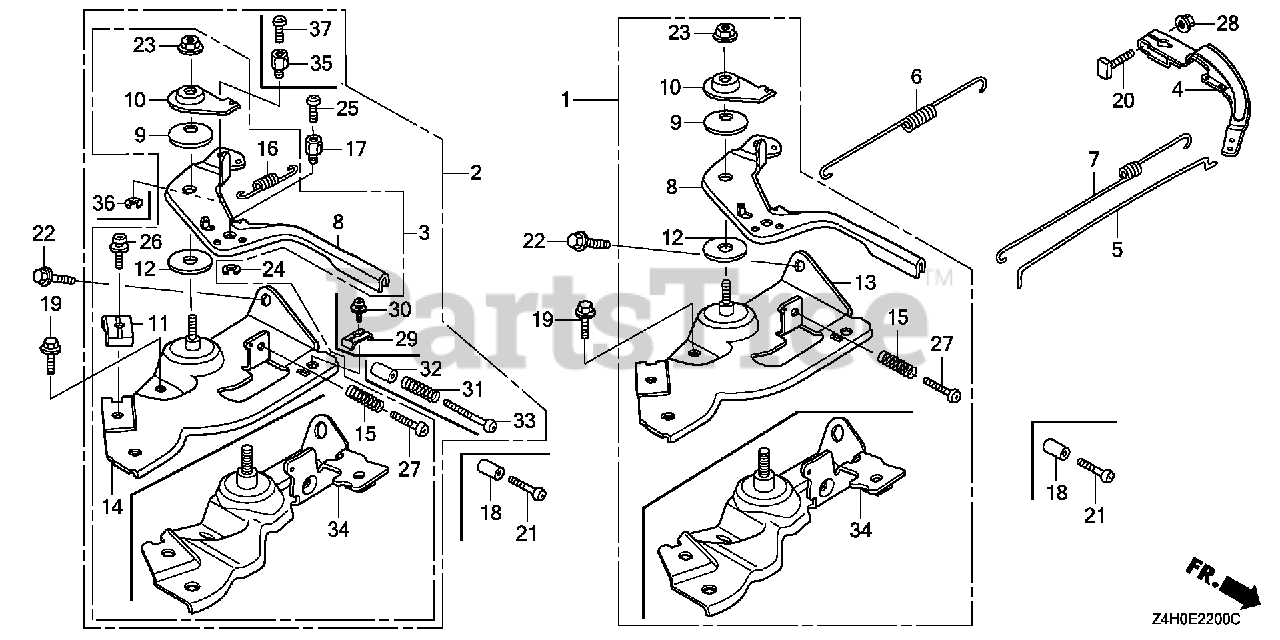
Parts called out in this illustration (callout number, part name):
1	CONTROL ASSY.
1	CONTROL ASSY. (COO)(FOR U.S.A.)
4	ARM, GOVERNOR
5	ROD, GOVERNOR
6	SPRING, GOVERNOR
7	SPRING, THROTTLE RETURN
8	LEVER, CONTROL
9	SPRING, LEVER
10	WASHER, CONTROL LEVER
12	SPACER, CONTROL LEVER
15	SPRING, CONTROL ADJUSTING
19	BOLT, FLANGE (6X12) (CT200)
20	BOLT, GOVERNOR ARM
22	BOLT, FLANGE (6X20) (CT200)
23	NUT, SELF-LOCK (6MM)
27	SCREW, PAN (5X25)
28	NUT, FLANGE (6MM)
34	BASE, CONTROL
